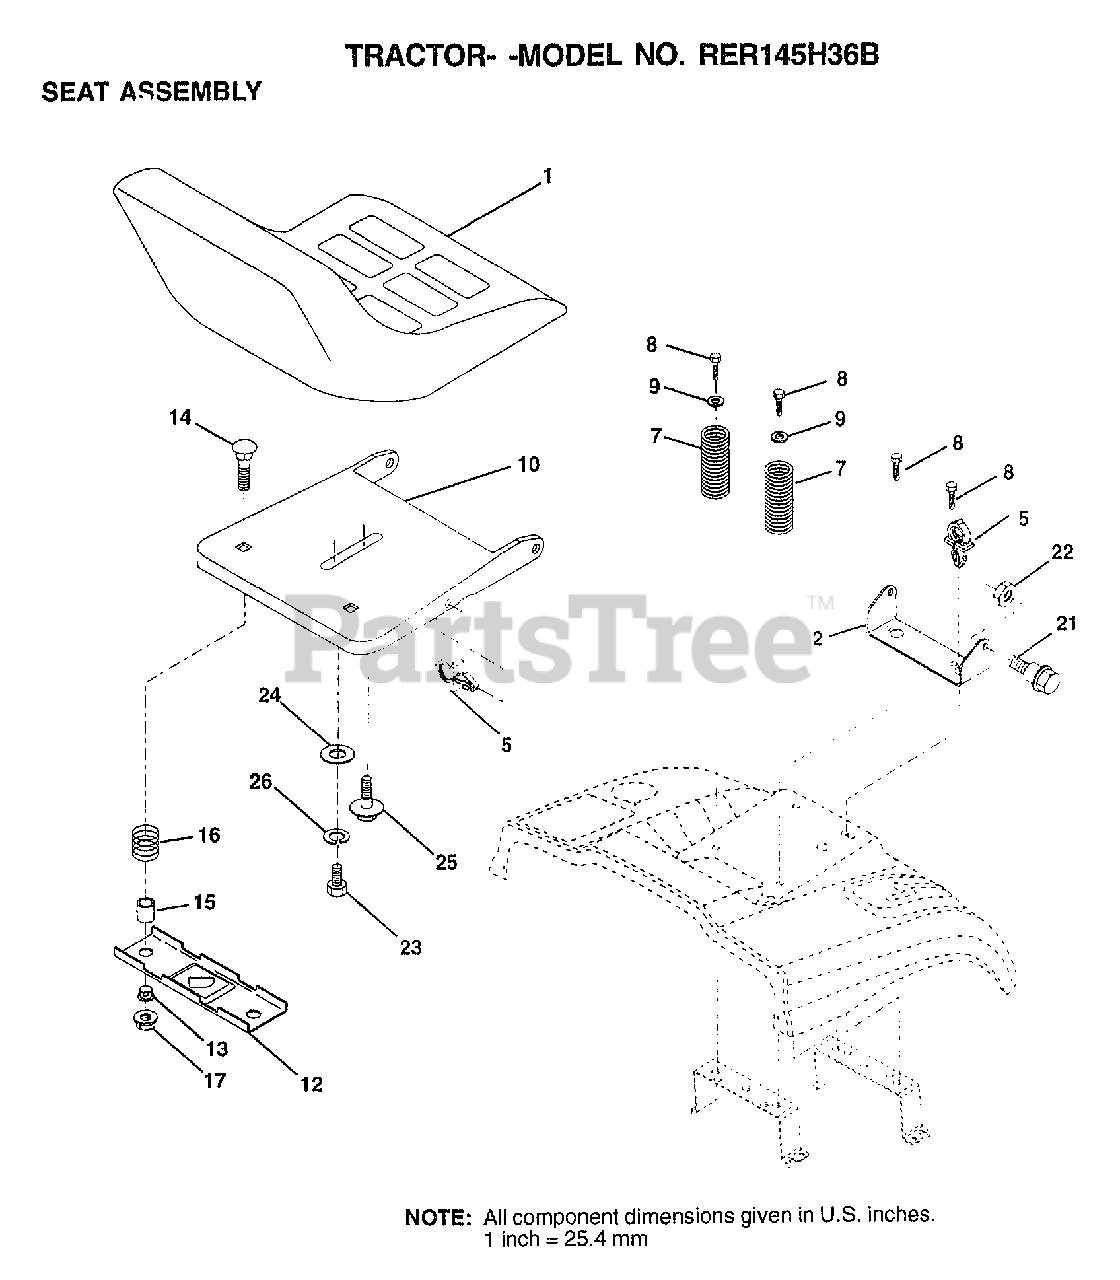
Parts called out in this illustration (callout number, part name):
2	BRACKET PVT SEAT
5	CLIP.PUSH-IN.HING
7	SPRING COMPRESSIO
8	SCREW
9	WASHER
10	PAN-SEAT
12	BRKT SWITCH
13	BUSHING
14	BOLT-RD HD SQ NK
15	SPLIT SPACER
16	SPRING
21	BOLT
22	NUT
23	BOLT
24	WASHER
25	"BOLT,SHOULDER"
26	LOCKWASHER
